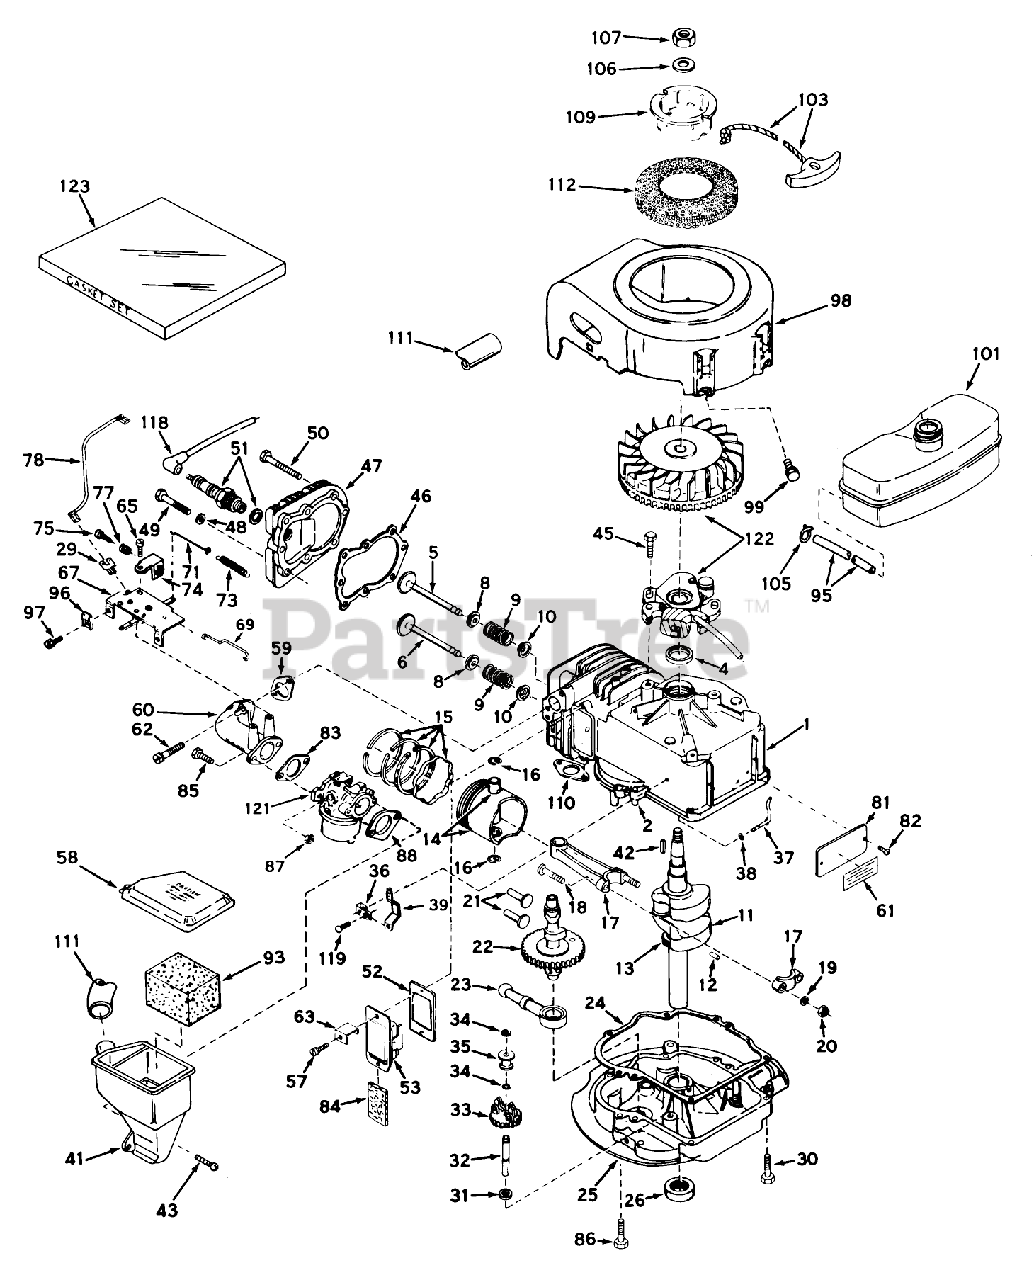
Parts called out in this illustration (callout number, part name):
1	Cylinder Assy. (Incl. Nos. 2, 4 103)
2	Pin-Dowel
4	OIL SEAL
5	Valve, Intake (Incl. Ref. #38, 39 40) (Std.)
5	Valve, Intake(1/32"overs.)(Incl. Ref. 8, 9 10)
6	Valve, Exhaust (Standard)(Incl. Ref. 8, 9 10)
6	Valve, Exhaust (1/32" Overs.(Incl. Ref. 8, 9 10)
8	Cap-Upper Valve Spring
9	Spring-Valve
10	Cap-Valve, Spring
11	Crankshaft Assy. (Incl. Ref. 12 13)(Model LAV35-40455H)
12	Pin, Groove
13	Gear, Crankshaft
14	Piston Pin Assy. (Incl. 2 of No. 16)(Standard)
14	Piston Pin Assy. (Incl. 2 of No. 16)(.010 oversize)
14	53020 ADN. TO 28594
15	Piston Ring Set Std.
15	Piston Ring Set .010 O.S.
15	Piston Ring Set .020 O.S.
16	Ring-Retaining, Piston Pin
17	Rod Assy., Connecting (Incl. Ref. #17)
18	Bolt, Connecting
19	Washer
20	LOCKNUT
21	Lifter-Valve
22	Camshaft
23	Oil Pump ASM
24	Gasket, Mounting
25	Flange Assy., Mounting (Incl. #26 32)
26	Seal Oil
29	Terminal
30	Screw (1/4-20 x 1-1/4)
31	Washer-Flat
32	Shaft-Governor
33	Governor Gear ASM
34	Ring, Retaining
35	Spool-Governor
36	Clamp-Lever, Governor
37	Rod, Governor (Incl. No. 36)
38	Washer-Flat
39	Governor Lever
41	Body, Air Cleaner
42	Key Flywheel
43	Screw, Fil. Hd. Sems
45	Screw
46	Gasket-Cylinder Head
47	CYLINDER HEAD
48	Washer
49	Screw
50	Screw Hex Hd. Cap
51	SPARK PLUG
52	Gasket Breather
53	Breather Assembly (Incl. Nos. 52 84)
57	Screw
58	Cover, Air Cleaner
59	Gasket, Intake
60	Pipe, Intake
61	480B GIL SNWTHWR O/
62	Screw (1/4-20 x 1)
63	Retainer Clip
65	Screw (10-24 x 9/16)
67	Control Assy., Speed
69	Link Governor
71	Link-Governor
73	Spring, Governor
74	Brachet, Control
75	Screw, Hex Hd.
77	Spring
78	Wire, Ground
81	IDENTIFICATION PLATE
82	Stud
83	Gasket
84	Element-Breather
86	Screw
87	Nut and Lock Washer (1/4-28)
88	Gasket-Air Cleaner
93	Element, Air Cleaner
95	Line-Fuel (8.62)
96	Conduit
97	Screw (10-32 x 3/8)
98	Housing, Blower
99	Screw (1/4-20x19/32)
101	Tank, Fuel
103	Rope Assy., Starter
105	Clamp-Line, Fuel
106	Washer
107	Hex Nut
109	Pulley Starter
110	Gasket Exhaust
111	Tube, Air Cleaner
112	Screen, Air
118	Cover-Spark Plug
119	Screw
121	Carburetor
122	Magneto
123	Gasket Set
